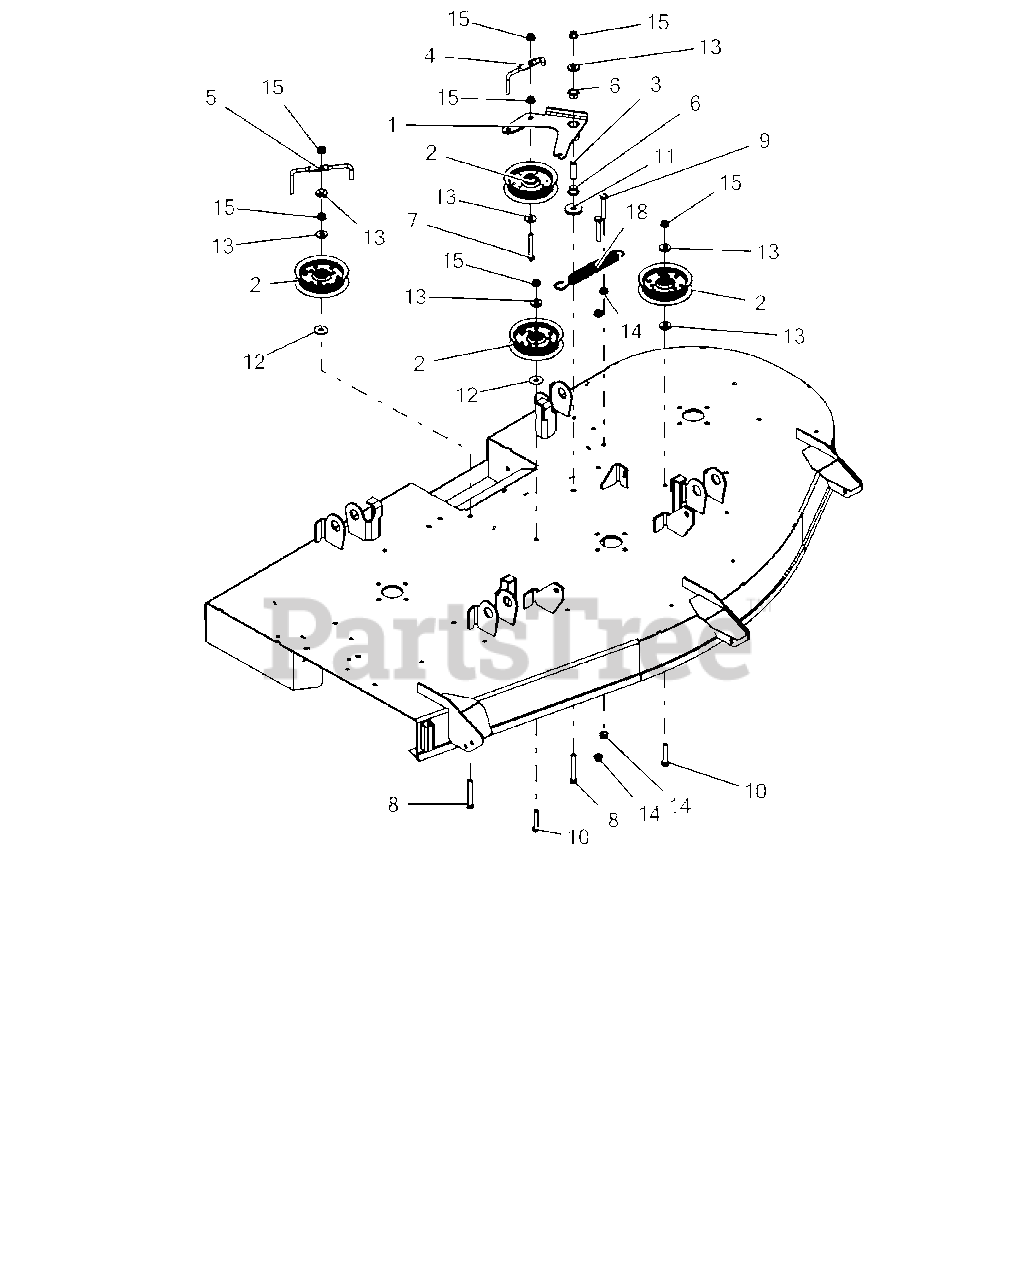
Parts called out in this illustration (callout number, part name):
1	WLDMT, IDLER ARM-42"
2	ASM, IDLER 4"
3	SPACER, .375IDX.625ODX1.66 PM
4	WIREFORM, BELT FINGER
5	WIREFORM, BELT FINGER
6	BSHG-FLG, .625X.750X.500X1.00
7	@BLT-HEX .38-16X2.50 GR5 YWZC
8	@BLT-HEX .38-16X2.75 GR5 YWZC
9	@BLT-HEX .38-16X2.25 GR5 YWZC
10	@BLT-HEX .38-16X2.00 GR5 YWZC
11	WSHR,FLT STL.406X1.50X.245YWZC
12	@WSHR-FL-STL .406X1.25X.10 ZC
13	WSHR-FL-STL .406X1.00X.188 YWZ
14	@NUT-SPNLK-FLG .375-16 YWZC
15	@NUT-LK-TOP-FLG .38-16 YWZC
18	SG-TENS .135X.98X6.0 WLD 62
